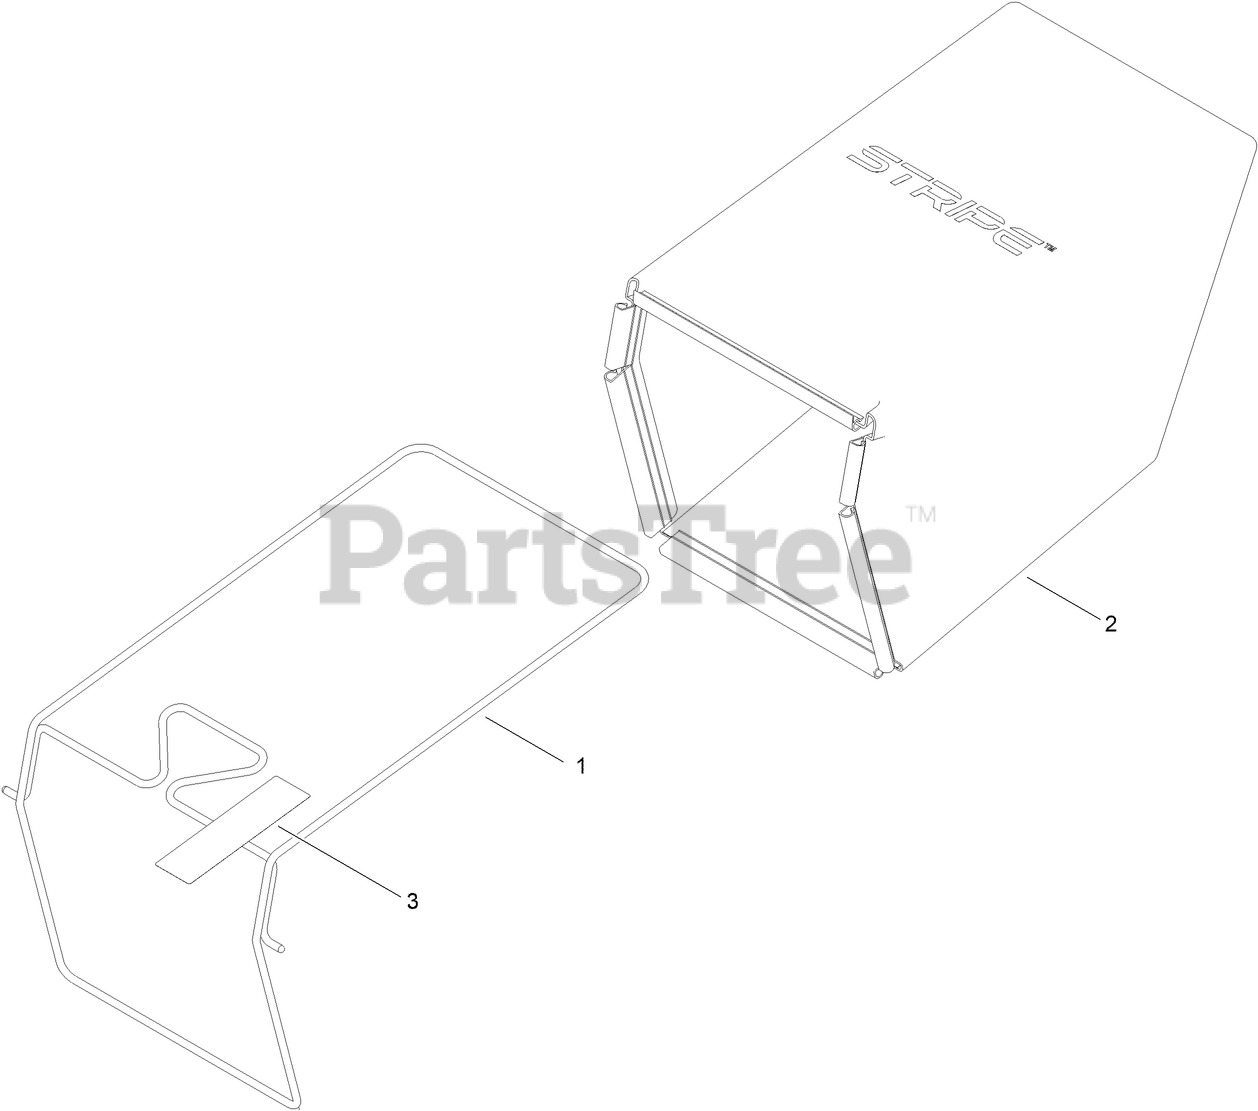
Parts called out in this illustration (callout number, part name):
1	ASM-FRAME
2	ASM-BAG
3	Decal-Warning
